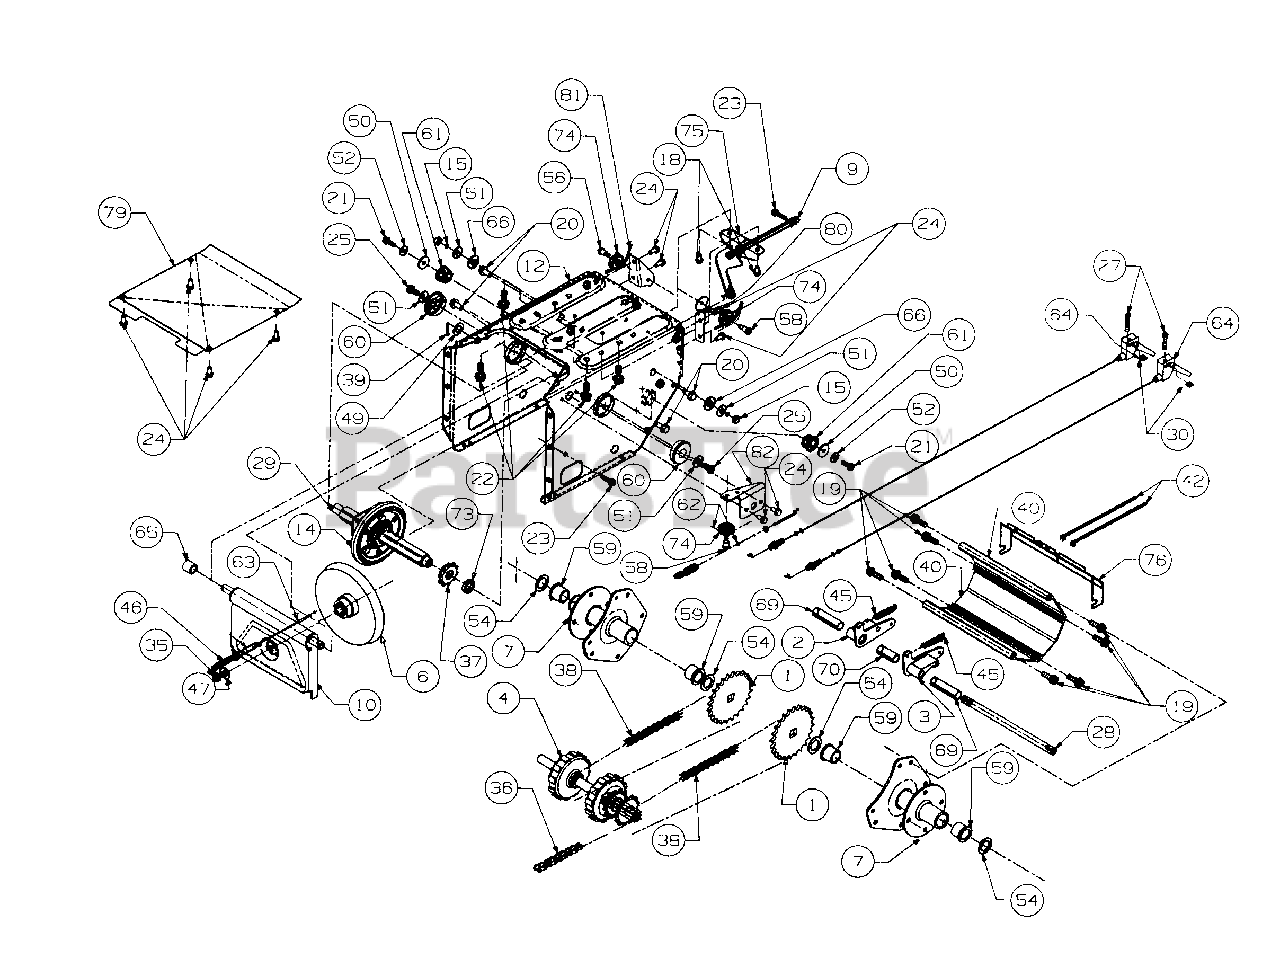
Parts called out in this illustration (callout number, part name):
1	Axle Assembly
2	Dog Assembly - R.H.
3	Dog Assembly - L.H.
4	Shaft Assembly
6	Disc Assembly
14	Wheel Assembly Friction
15	Screw
20	Screw
25	Screw
30	Nut Flange
39	Pin Cotter
40	Housing Track
42	Cable Tie
45	Spring
46	Spring
47	Washer-Bell
49	Washer-Flat
50	Washer-Flat
51	Washer-Bell
52	Washer-Bell
54	Washer-Flat
56	Lubricant
58	Screw-Shoulder
59	Bearing-Flange
60	Bearing Ball
61	Bearing-Hex Flange
62	Cable-Auger Clutch
63	Cable-Drive Clutch
64	Cable with Trigger Lever
66	Spacer-Shoulder
69	Spacer Spit
70	Spacer-Split
73	Spacer
74	Roller-Cable
